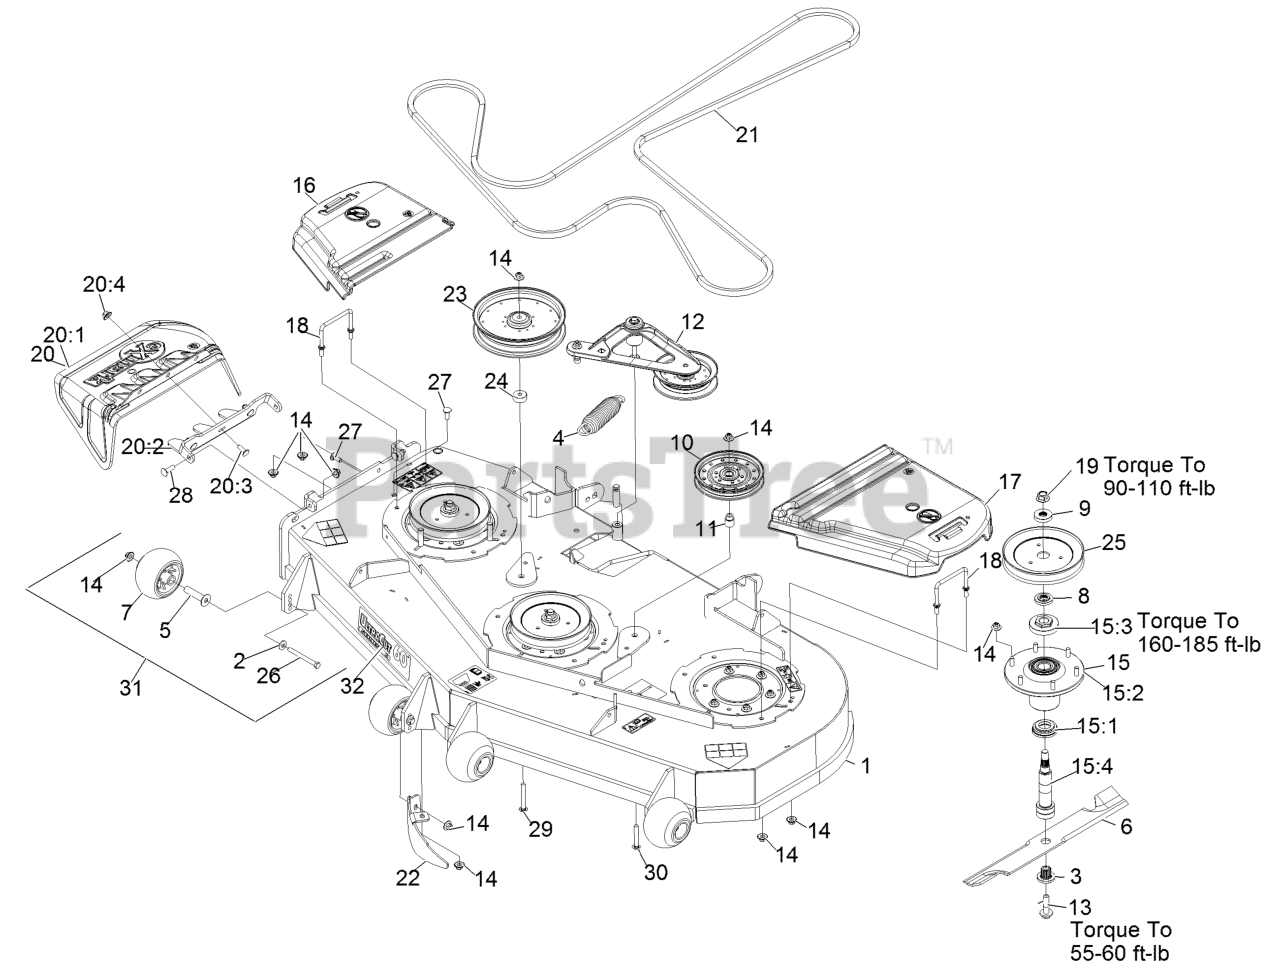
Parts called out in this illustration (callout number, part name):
1	DECK ASM,W/DECALS 60
2	WASHER-BELLEVILLE
3	BUSHING,SPLINED
4	SPRING-EXTENSION
5	AXLE, ROLLER
6	Blade-Extreme 2, 20.50"
7	ROLLER-SCALP, ANTI
8	SPACER,SPLINED STEPPED
9	SPACER,SPLINED
11	BUSHING-IDLER
12	DECK IDLER ASM
13	SCREW,SEMS 1/2-20 X 2.19
14	Nut-Nyloc 3/8-16 Flg
15	ASM,SPINDLE HOUSING
15:1	GUARD,BOTTOM
15:2	ASM,CUTTER HOUSING
15:3	NUT, SPINDLE 7/8-14
15:4	SPINDLE,DOUBLE SPLINE
16	COVER-BELT, RH
17	COVER-BELT, LH
18	WIREFORM-COVER
19	NUT-FLANGE, CENTERLOCK
20	ASM,DISCHARGE CHUTE
20:1	CHUTE,DISCHARGE
20:2	BRACKET,DISCHARGE CHUTE
20:3	SCREW-CARR
20:4	Nut-Nyloc 3/8-16 Flg
21	BELT,V-5V-198.75
22	DOGLEG - LZ60
23	PULLEY-IDLER
24	SPACER-IDLER
25	SHEAVE,BLADE DRIVE 7.25
26	SCREW-HH 3/8-16 X 3 3/4 GR 8
27	SCREW-CARR
28	Bolt-Carriage 3/8-16 X 1 1/4
29	SCREW-CARR
30	SCREW-CARR
31	KIT, ANTI-SCALP ROLLER
32	DECAL,ULTRACUT 60 SERIES
